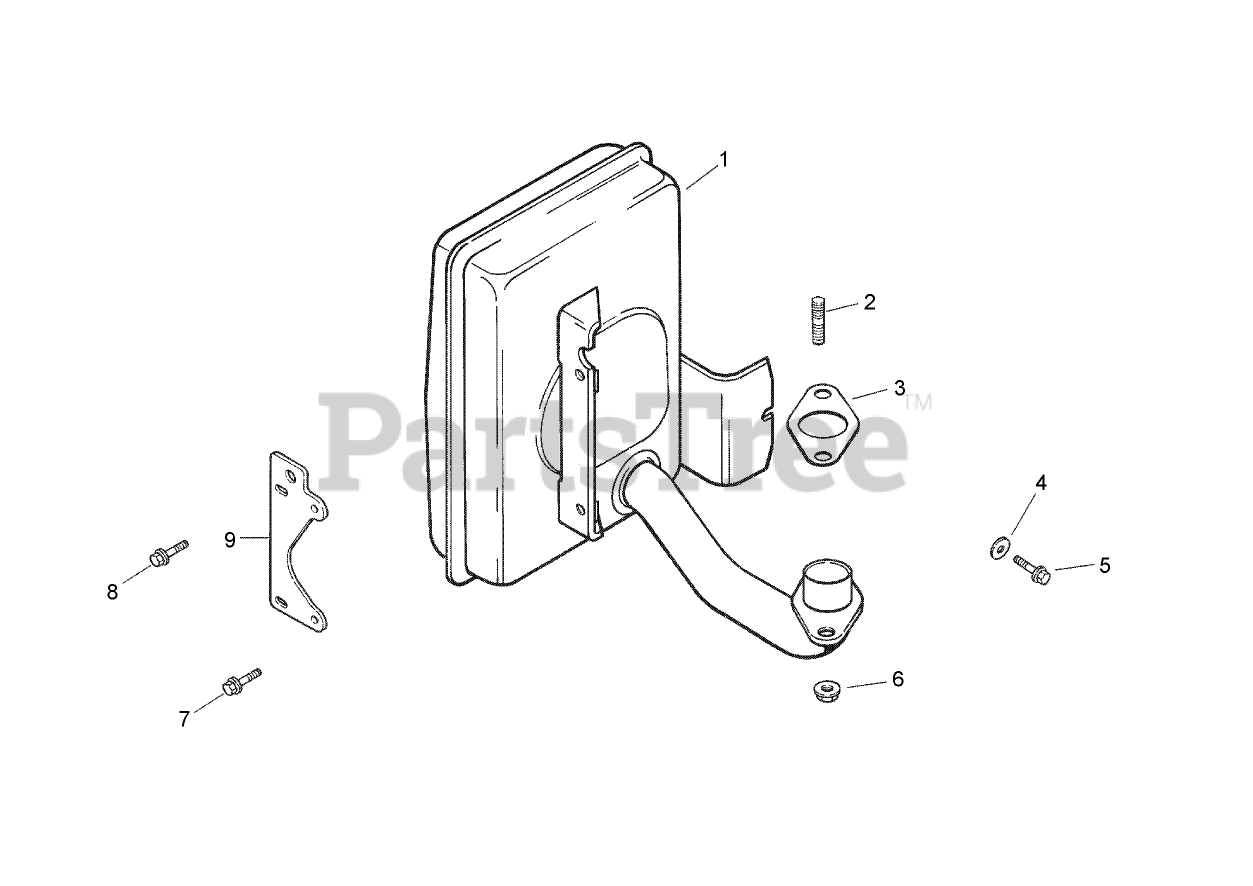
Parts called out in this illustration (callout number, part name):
1	Muffler
2	STUD (M8X1.25X33)
3	Gasket-Manifold, Exhaust
4	Washer-Plain (1/4in)
5	SCREW-FLANGE, THREAD FORMING (M5X0.8X16)
6	NUT-FLANGE (M8X1.25)
7	SCREW-FLANGE, THREAD FORMING (M6X1.0X16)
8	SCREW-FLANGE, THREAD FORMING (M6X1.0X25)
9	Bracket-Muffler
